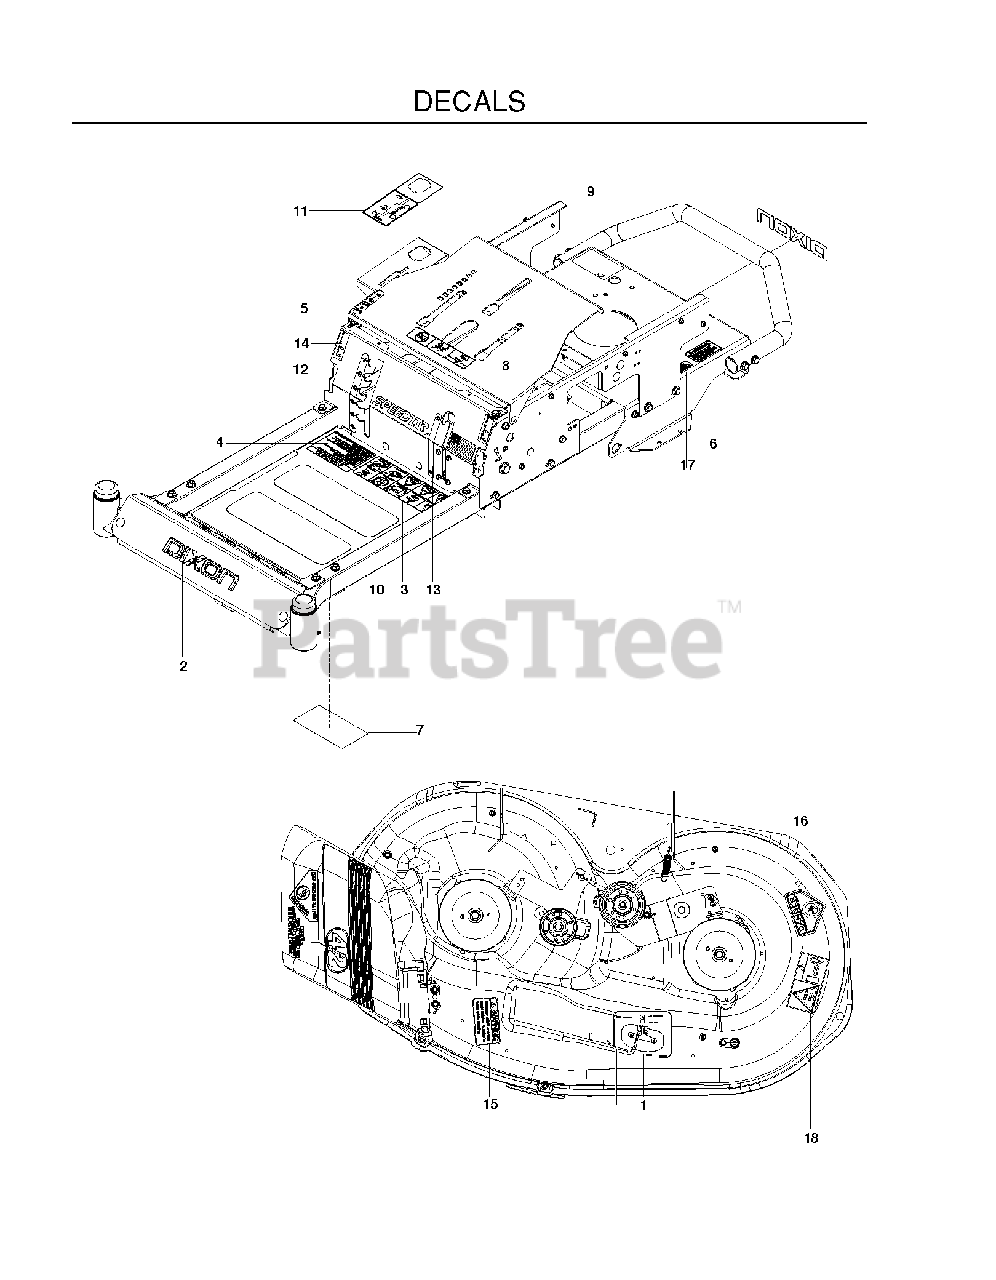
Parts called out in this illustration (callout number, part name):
1	DECAL, BELT ROUTING
2	DECAL, DIXON LOGO, DOMED
3	DECAL, SAFETY WARNING
4	DECAL, WARNING
5	DECAL, PARK BRAKE
6	DECAL, PROP. 65
7	DECAL, SERVICE
8	DECAL, BATTERY
9	DECAL, DO NOT MOUNT
10	ANTI-SKID PAD
11	Decal, Control Panel Hus
12	DECAL, DECK HEIGHT
13	DECAL, BLADE ENGAGEMENT
14	DECAL, MOTION CONTROL
15	DECAL, CAUTION
16	DECAL, CPSC
17	DECAL, WARNING SPARK ARRESTOR
18	DECAL, EURO SEVERING
